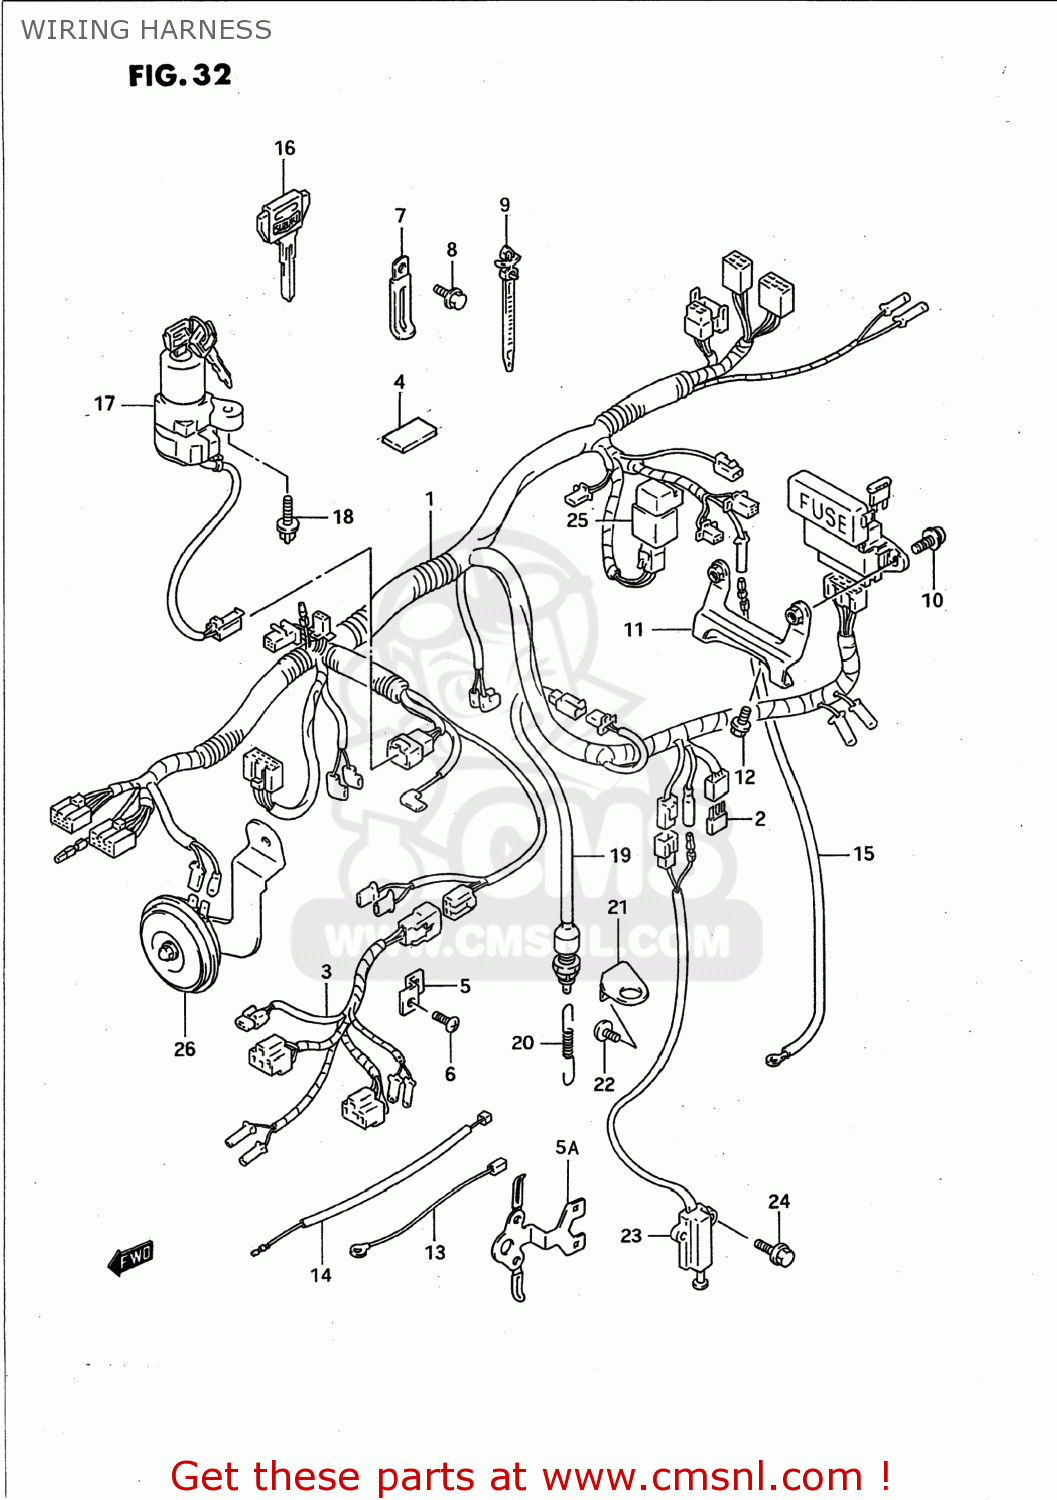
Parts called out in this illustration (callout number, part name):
1	HARNESS,WIRING NO.1
2	DIODE(STANLEY DE8804)
3	HARNESS,WIRING NO.2
4	TAPE
5	HOLDER,COUPLER
5A	HOLDER COMP,COUPLER
6	SCREW
7	CLAMP
8	BOLT
9	CLAMP(L:90)
10	VIS
11	BRACKET,FUSE BOX
12	BOLT
13	WIRE,LEAD
14	WIRE
15	WIRE,WATER TEMP GAUGE LEAD
16	KEY,BLANK
17	LOCK ASSEMBLY,STEERING
18	BOLT M8X20
19	SWITCH ASSY,STOP LAMP
20	SPRING
21	BRACKET,STOP LAMP SWITCH
22	SCREW(6X12)
23	SWITCH ASSEMBLY,SIDE STAND
24	BOLT
25	RELAY ASSY
26	HORN ASSEMBLY,LOW PITCH
